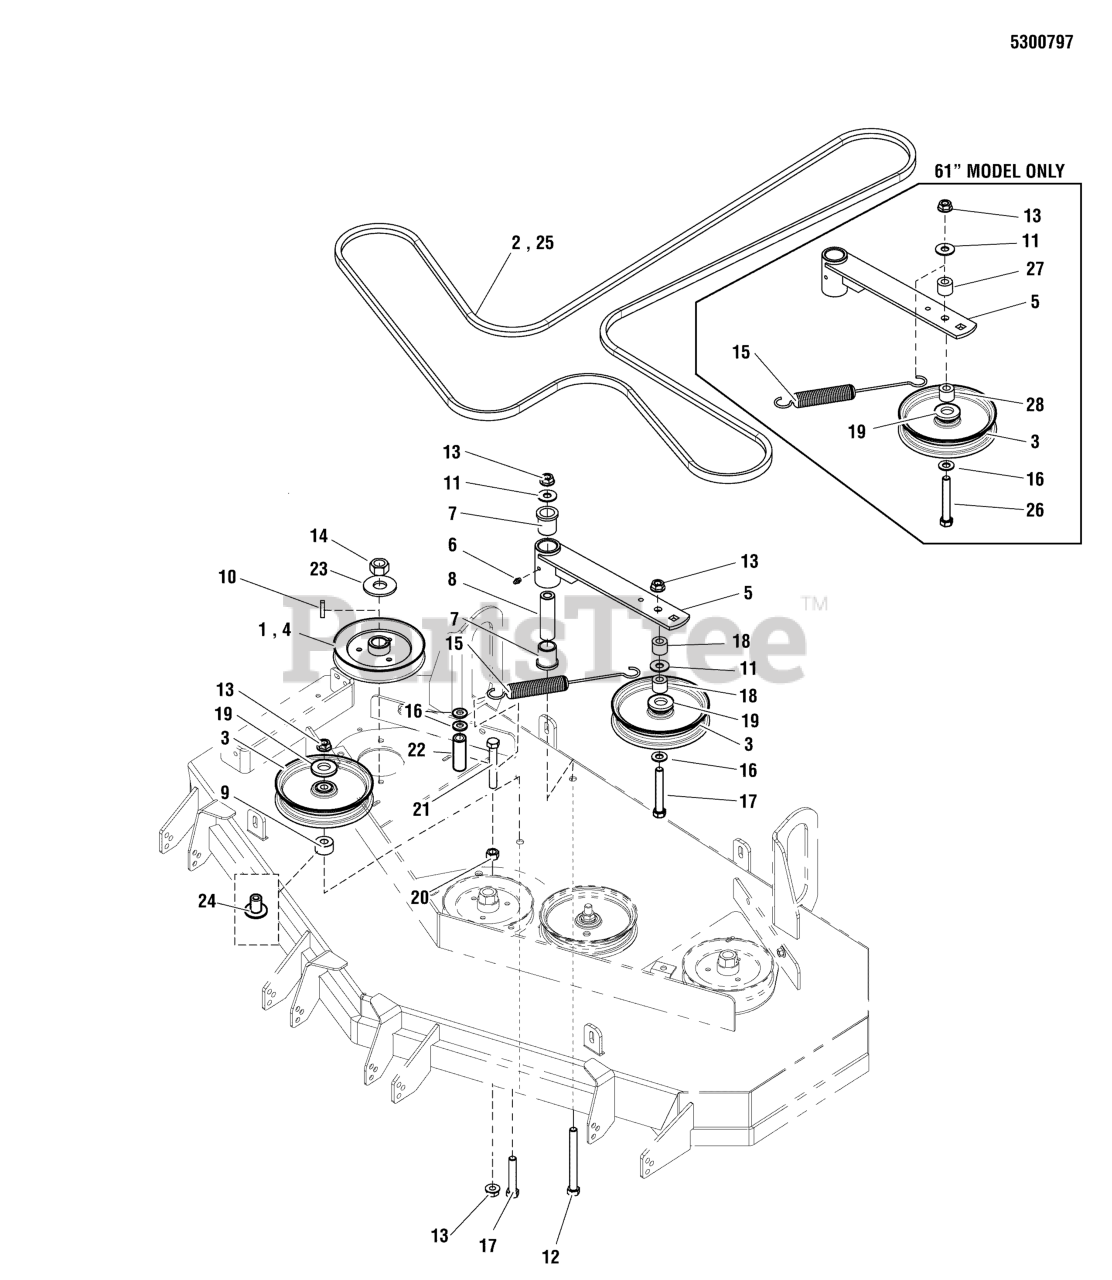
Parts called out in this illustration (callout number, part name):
1	PULLEY, 6.93 EOD X 25MM, SPLIT
2	BELT, # 7-6196
4	PULLEY, 6.122 OD X .98 BORE
5	WELD, IDLER ARM - RED
6	GREASE FITTING, 1/4-28 STRAIGHT
7	BUSHING, FLANGE
8	SPACER, .52 X 1.00 X 3.42
9	SPACER, .52 X 1.25 X .70
10	KEY, 1/4" SQ. X 1-1/4
11	WASHER, 1/2" USS
12	BOLT, 1/2-13 X 4-1/2" GD5
13	NUT, Hex Flange, Nylock, 1/2-13
14	NUT, 3/4-16 HEX
15	SPRING, EXTENSION, SWIVEL END
16	WASHER, 1/2 SAE
17	BOLT, 1/2-13 X 2-3/4 GD5 CZ
18	SPACER, .52 X 1.00 X .44
19	SHIELD, PULLEY BEARING
20	NUT, 1/2-13 HEX
21	BOLT, 1/2-13 X 4" GD5 CZ
22	HOSE, 1/2" PUSH-LOCK, 2.50"
23	WASHER, 3/4 BELLEVILLE
24	IDLER MOUNT
25	BELT, 1793.9 #7-8774
26	BOLT, 1/2-13 X 3-1/2, HEX HD, GD5, CZ (SV)
27	SPACER, .52 X 1.00 X .38
28	SPACER, .52 X 1.00 X 1.00
